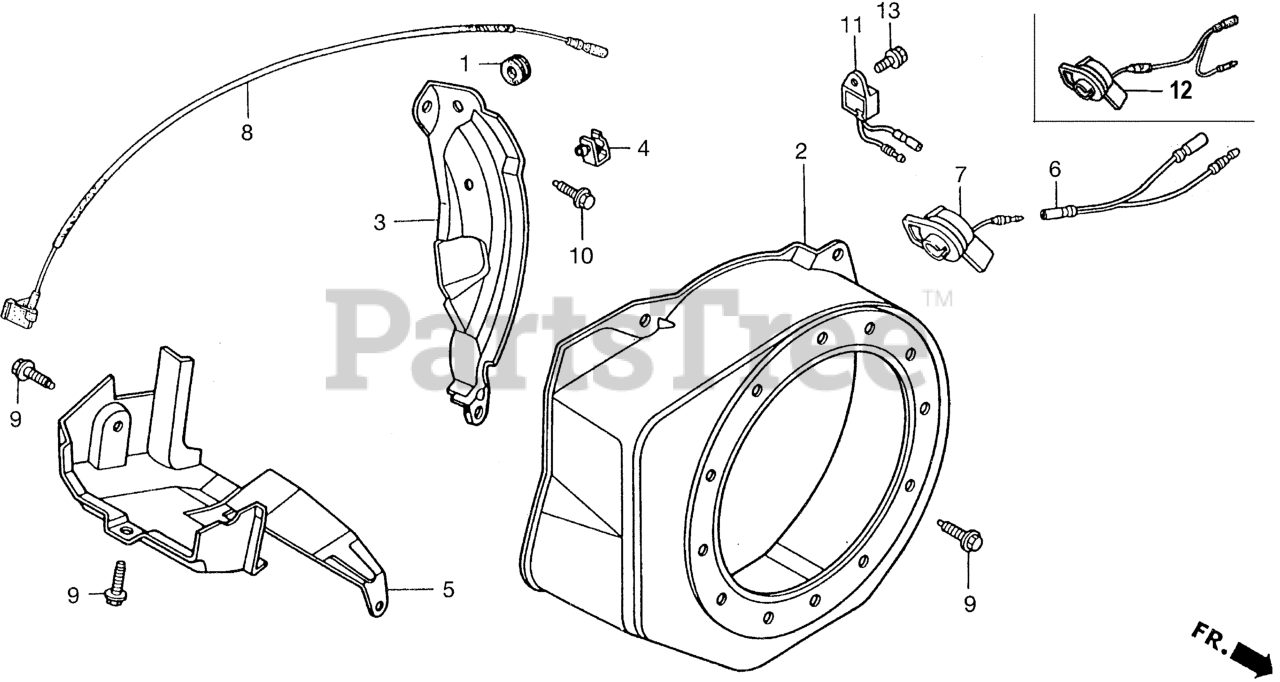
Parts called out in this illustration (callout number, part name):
1	GROMMET, ADJUSTING COVER
2	COVER, FAN *R280* (POWER RED)
3	PLATE, SIDE (OIL ALERT)
4	CLAMP, CORD
4	CLIP, HARNESS
6	SUB-HARNESS
7	SWITCH ASSY., ENGINE STOP Use from Engine SN 2092216 to 2359126.
7	SWITCH ASSY., ENGINE STOP
8	WIRE, STOP SWITCH (370MM)
9	BOLT, FLANGE (6X12) (CT200)
10	BOLT, FLANGE (6X20) (CT200)
11	ALERT UNIT, OIL
13	BOLT, FLANGE (6X8)
